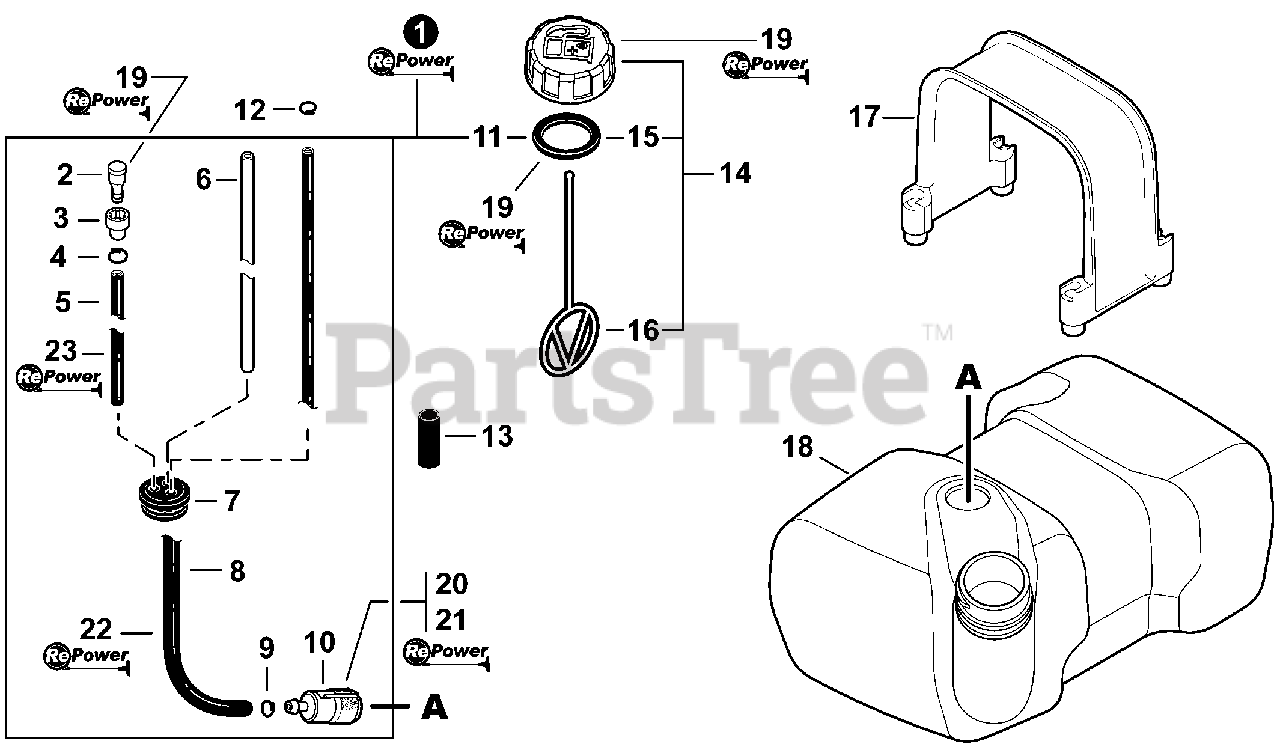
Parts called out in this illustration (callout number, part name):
1	FUEL SYSTEM KIT - REPOWER
2	VENT ASSY
3	HOLDER, VENT
4	CLIP 6.5MM
5	PIPE, FUEL VENT 3×6×130
6	PIPE, FUEL RETURN 2.4×5×170
7	GROMMET, FUEL
8	PIPE, FUEL 3×5×240 BLACK
9	CLIP 6MM
10	FILTER, FUEL 125-528
11	GASKET, FUEL CAP
12	CLIP 6MM
13	TUBE, FUEL LINE 16×18×L40
14	CAP ASSY, FUEL
15	GASKET, FUEL CAP
16	CONNECTOR, CAP L= 100mm
17	RETAINER, FUEL TANK
18	TANK, FUEL
19	CAP/VENT KIT - REPOWER
20	TUNE-UP KIT - REPOWER
21	FILTER KIT - REPOWER
22	PIPE, BULK - REPOWER 3×5mm BLACK
23	PIPE, BULK - REPOWER 3×6mm BLACK
